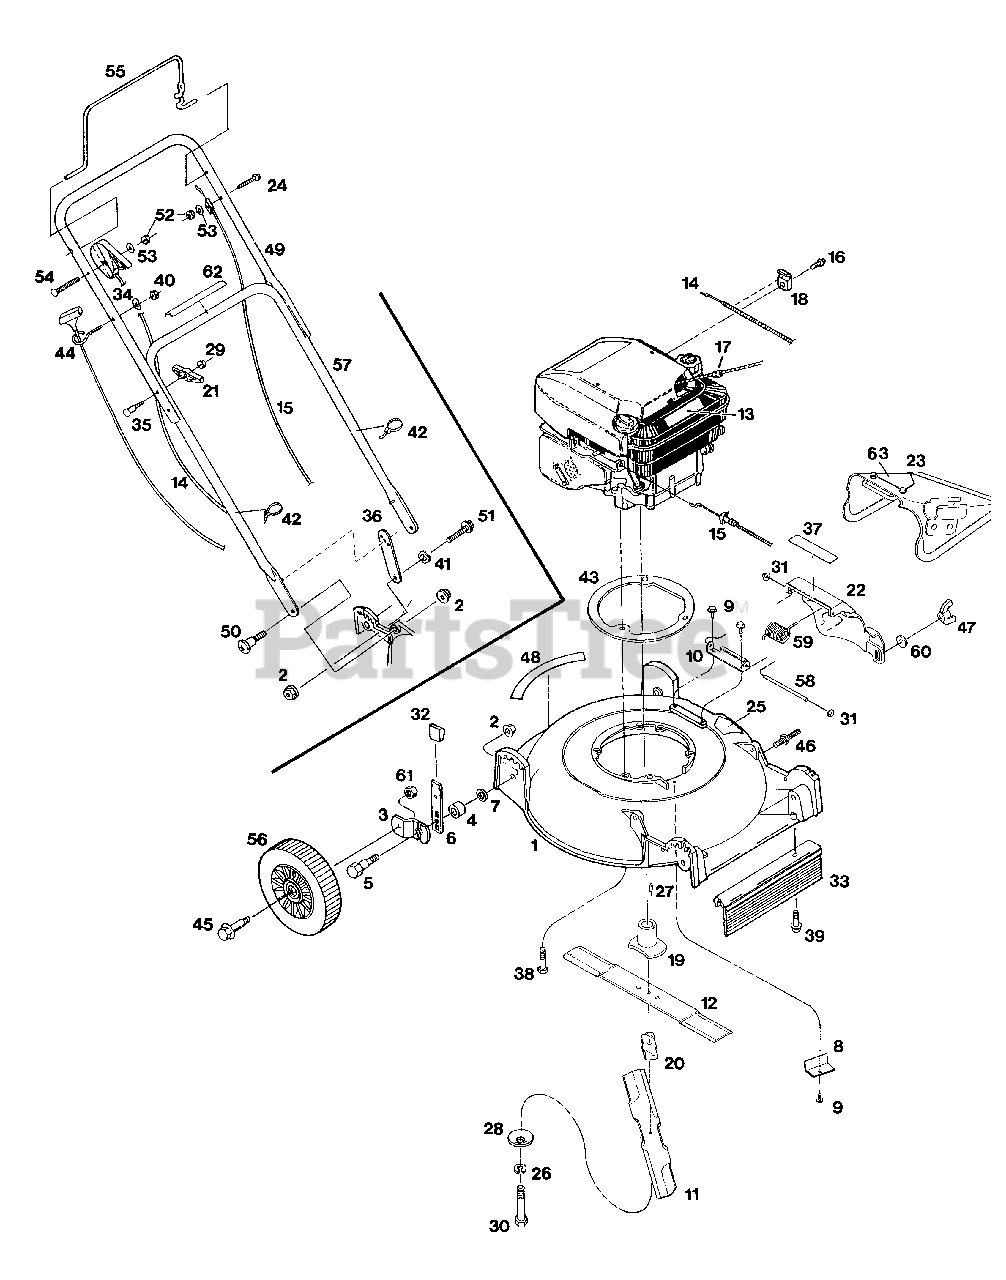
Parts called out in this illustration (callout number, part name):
1	Deck-20" orange
2	Nut-5/16" flg. Iock
3	Wheel arm
4	Spacer-wheel
5	Bolt-height adjuster
6	Setting lever assembly L.H.
6	Setting lever assembly R.H.
7	Washer-flat 5/16"
8	Cover-belt
9	Screw-1/4-20 x 3/4" hex tap
10	Bracket-hinge
12	Blade-recut 20"
13	Decal-blade warning
14	Control-throttle w/cable
15	Cable-engine/blade control
16	Screw-#10-16 x 5/8" tap
17	Rope stop
18	Cable clamp
19	Adapter-blade
20	Spacer-blade
21	Wing nut-plastic
22	Cover-mulch 20"
23	Chute deflector assembly
24	Screw-1/4-20 x 1-1/4" truss hd.
25	Decal-CPSC danger
26	Washer-3/8" lock H.D.
27	Key-woodruff #61
28	Washer-3/8" conical
29	Nut-5/16-18 hex
30	Bolt-3/8-24 x 3-1/2" HHCS Gr. 8
31	Nut-1/4 push-on
32	Plastic tip-height adjuster
33	Trailing shield-plastic
34	Washer-1/4" curved
35	Bolt-handle
36	Handle support
37	Decal-mulch cover danger
38	Bolt-3/8-16 x 1-3/4" HHCS Gr. 5
39	Screw-1/4-20 x 1/2" hex tap
40	Nut-1/4-20 lock
41	Washer-5/16" wave
42	Cable tie
43	Engine ring
44	Eyebolt-1/4-20
45	Bolt-wheel
46	Stud-1/4-20 x 3/4"
47	Nut-1/4-20 wing
48	Decal-logo 20"
49	Handle-upper
50	Bolt-handle mtg.
51	Bolt-handle support
52	Nut-1/4-20 hex
53	Washer-1/4" star
54	Screw-1/4-20 x 1-1/2" truss hd.
55	Bail-engine/blade control
56	Wheel-8" push
57	Handle-lower
58	Hinge rod
59	Spring-mulch cover
60	Washer-1/4" flat
61	Nut-3/8-16 hex lock
62	Decal-starting instructions
63	Decal-CPSC danger
